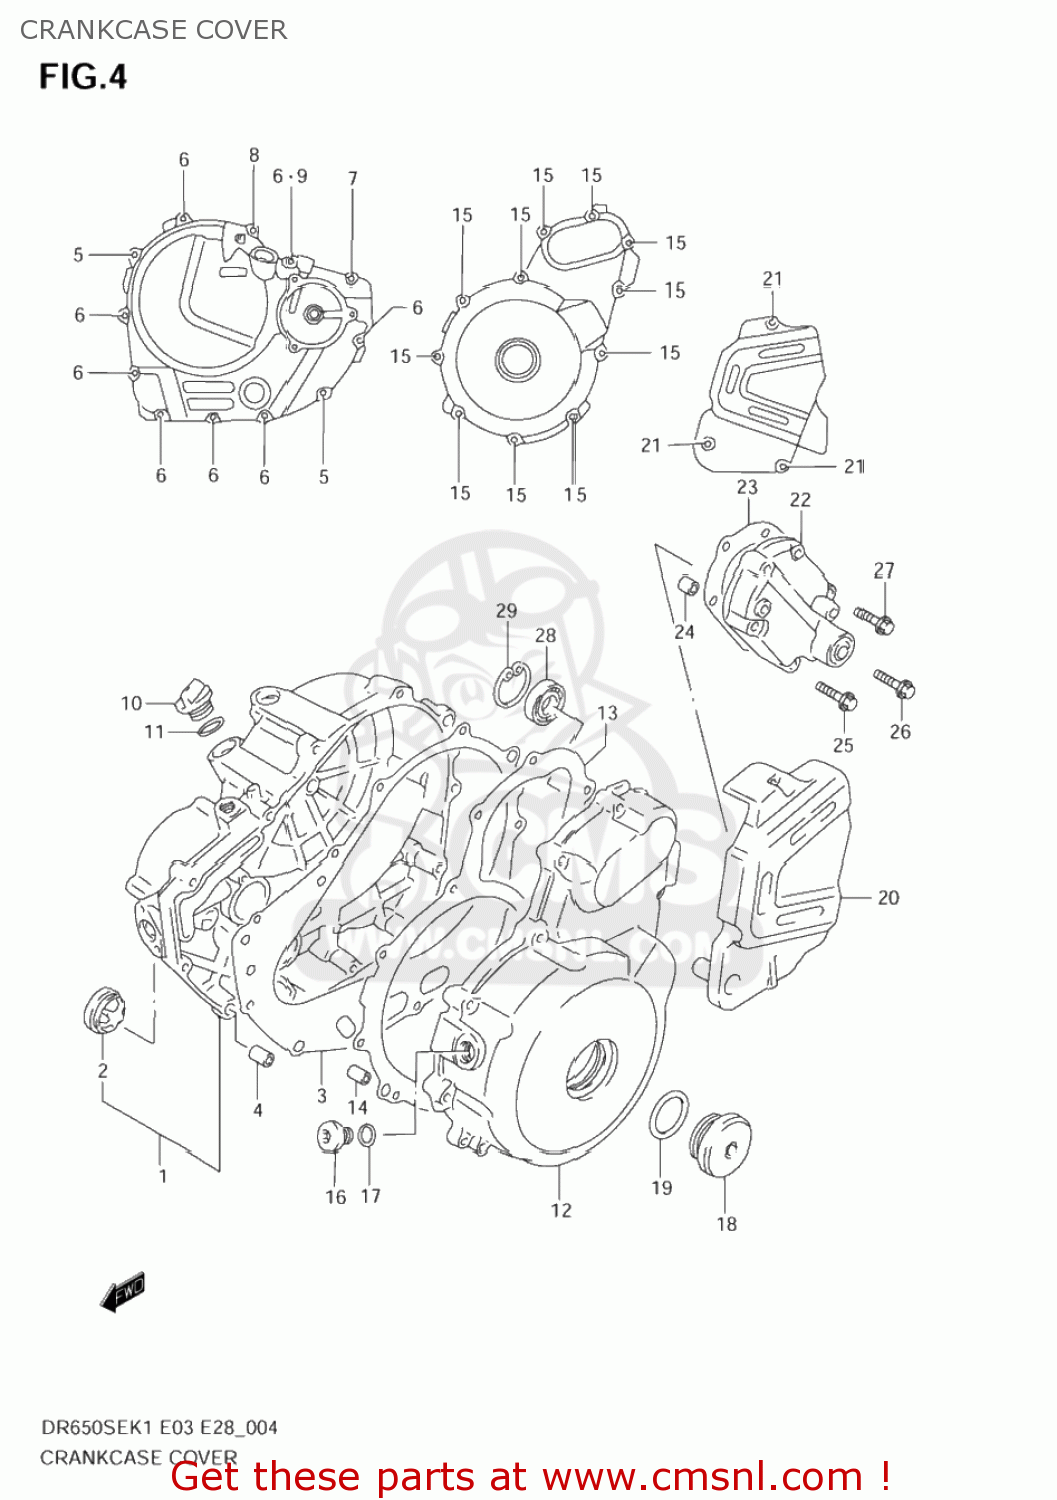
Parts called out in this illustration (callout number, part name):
1	COVER,CLUTCH
2	LENS,OIL LEVEL CHECK
3	GASKET,CLUTCH COVER
4	PIN
5	BOLT
6	BOLT
7	BOLT
8	BOLT
9	GASKET(5.8X13X1.2) (NAS)
10	PLUG
11	O RING(D:3.1,ID:16.8)
12	COVER,MAGNETO
13	GASKET,MAGNETO COVER
14	PIN
15	BOLT
16	PLUG
17	GASKET(13.8X18.8X4.8) (NAS)
18	PLUG(SILVER)
19	O RING(D:3.1,ID:32.7)
20	COVER,ENGINE SPROCKET
21	BOLT
22	COVER,GEAR SHIFT
23	GASKET,GEAR SHIFT COVER (NAS)
24	PIN
25	BOLT
26	BOLT,G/S SWITC
27	SCREW
28	BEARING(12X28X8)
29	CIRCLIP
